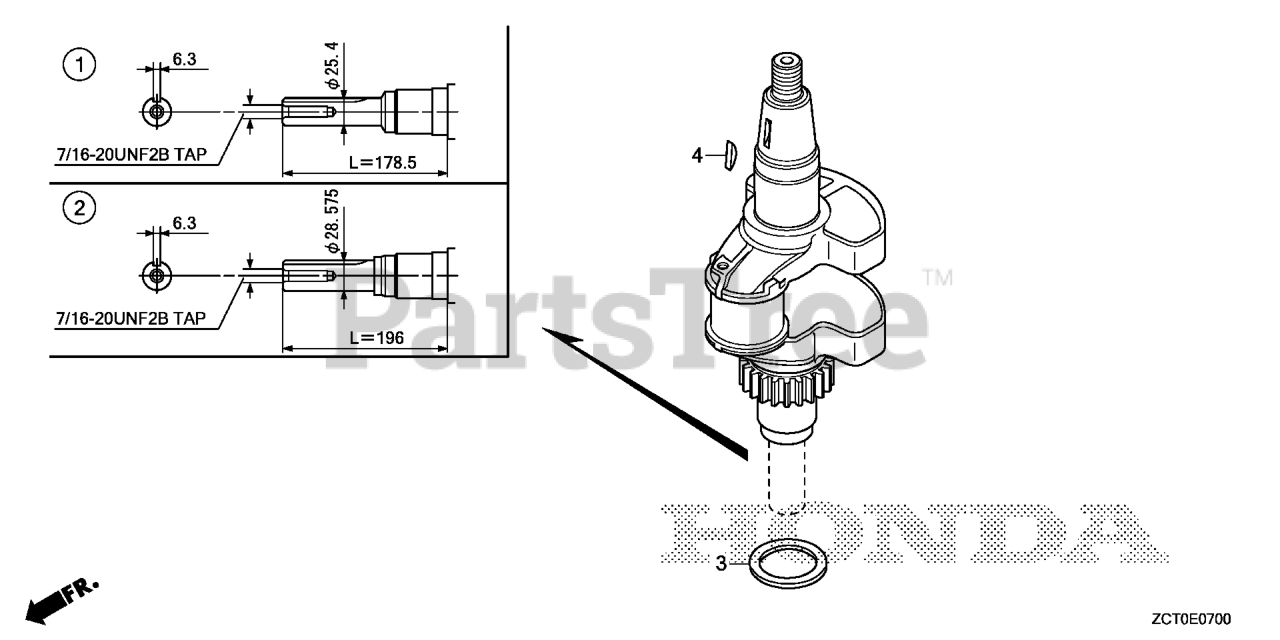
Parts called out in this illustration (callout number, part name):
1	CRANKSHAFT (L=178.5)
3	WASHER, CRANKSHAFT THRUST
4	KEY, SPECIAL WOODRUFF (25X18)
